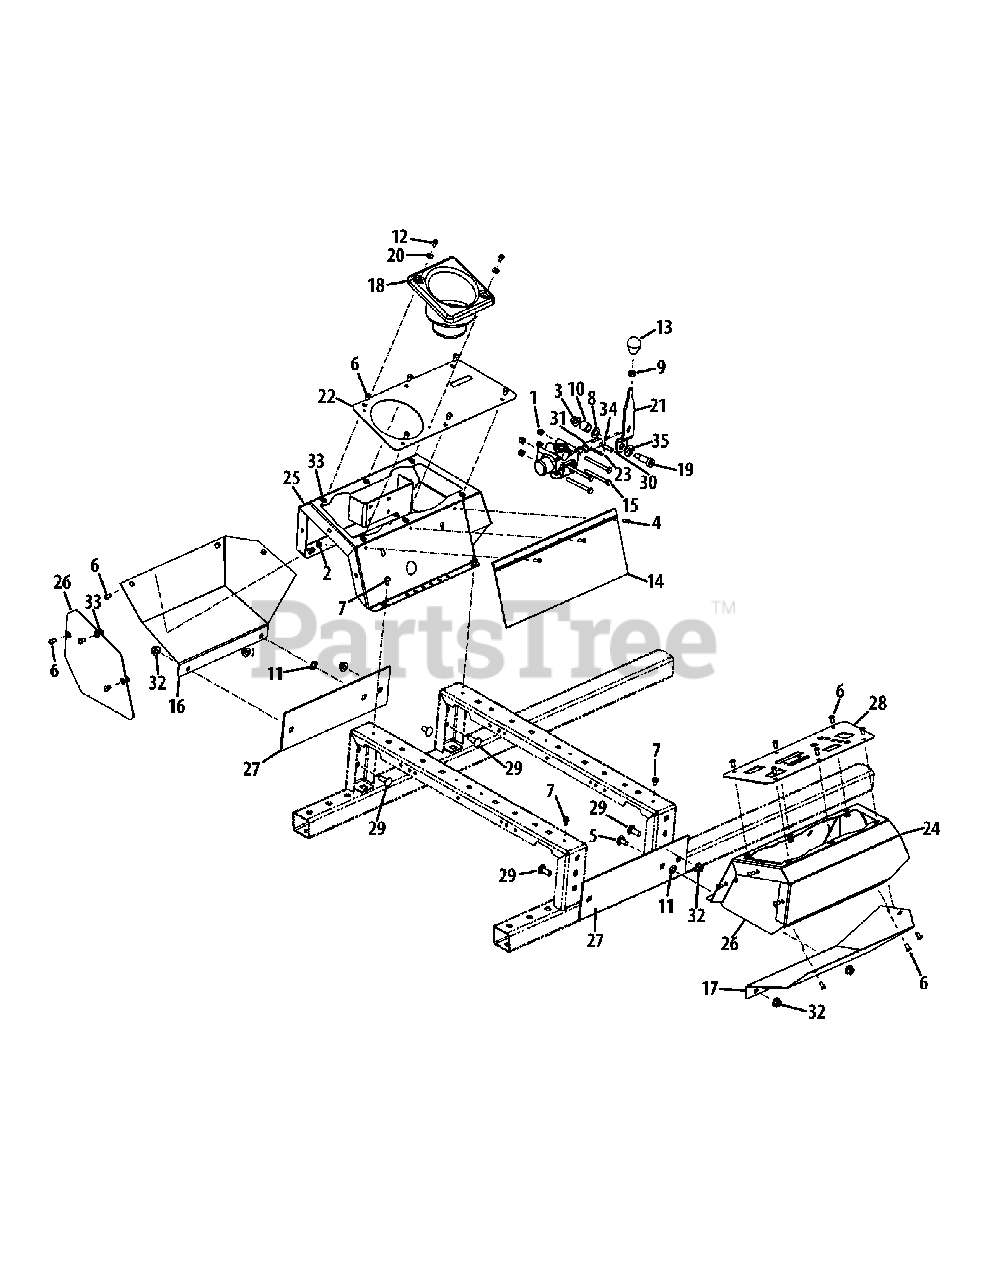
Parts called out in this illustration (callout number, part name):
1	Nut, 1/4-20
2	Nut, #10-32
3	Flange Counter Lock Nut, 3/8-16
4	Machine Screw, #10-32 x .625
5	Carriage Bolt, 3/8-16 x .75
6	Screw, 1/4-20 x .500
7	Hex Flange Screw, 1/4-20 x .500
8	Washer, .536 x .930 x .050
9	Jam Nut, 3/8-16
10	Spacer, .500 x .750 x .700
11	Push Nut, .335 x .780 x .015
12	Flange Screw, #10-32 x .500
13	Lever Knob, 3/8-16
14	Debris/Storage Bag
15	Hex Screw, 1/4-20 x 2.75
16	LH Lower Panel
17	RH Lower Panel
18	Cup Holder
19	Shoulder Bolt, 3/8-16 x .50 x 1.0
20	Washer, .300 x .550 x .047
21	Lift Valve Lever Bracket
22	LH Cover Control Plate
23	Spirol Pin, 3/16 x 1.0
24	RH Control Panel Assembly
25	LH Bracket Control Panel Assembly
27	Lower Side Panel
28	RH Cover Control Plate
29	Carriage Bolt, 3/8-16 x 1.00
30	Pin, .25 x .9375
31	Valve Link
32	Flange Lock Nut, 3/8-16
33	Nut, 1/4-20
34	Cotter Pin, 1/16 x .75
35	Bell Washer, .525 x 1.00 x .050
